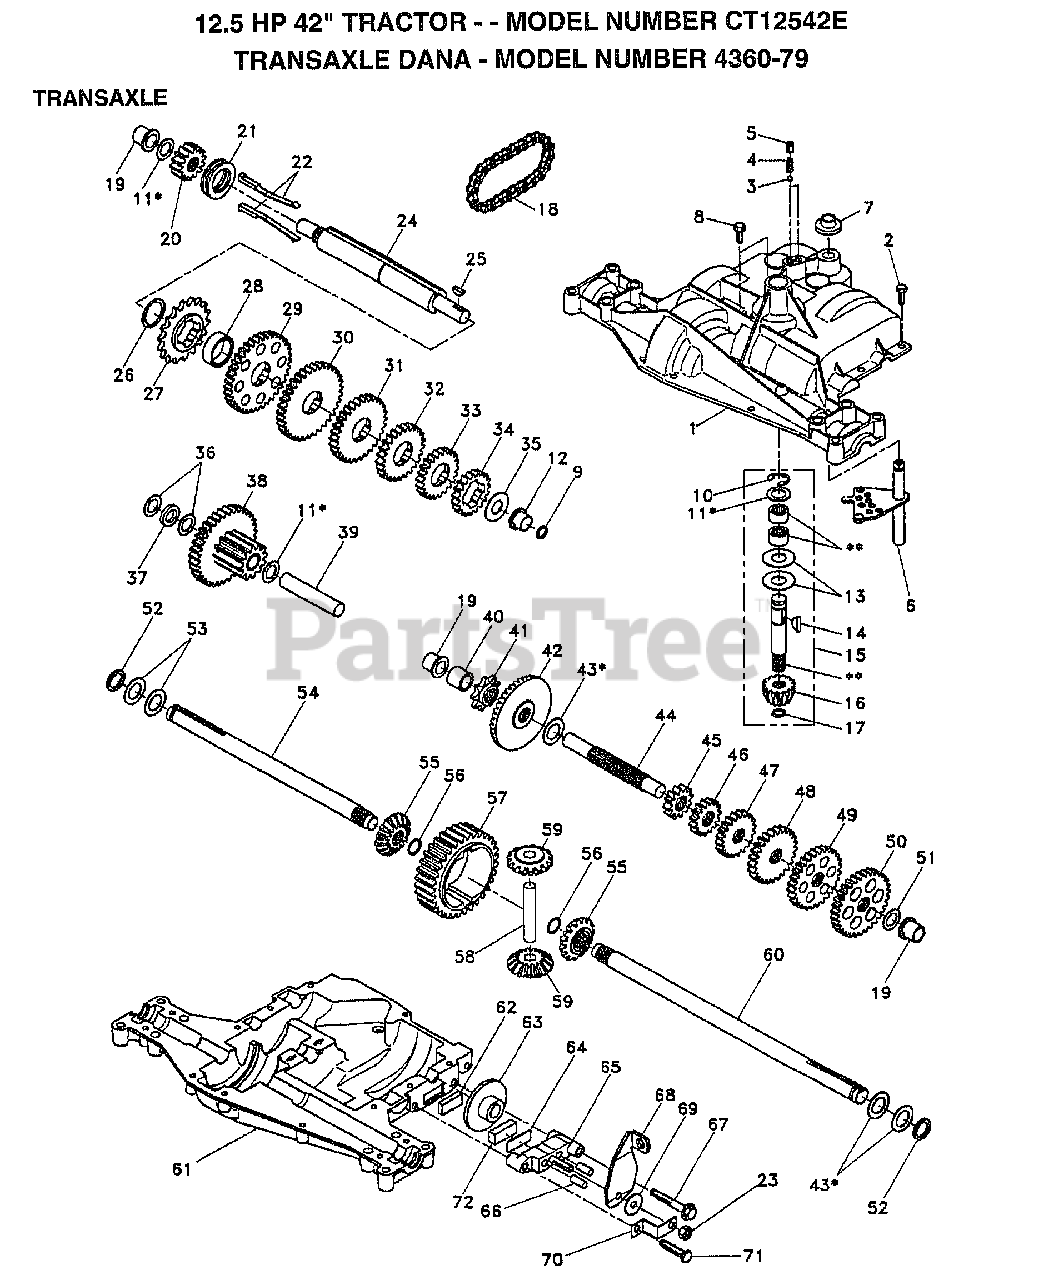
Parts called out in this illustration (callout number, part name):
1	HOUSING UPPER TRN
4	"SPRING, DETENT LT"
5	"SCREW, SET LT"
6	KIT SHIFTER ASM
7	SHIFTER BOOT
8	SCREW TAP W/SEAL
9	SQUARE RING
11	ASM KIT SHIM 4689
12	BEARING FLAN-DANA
13	WASHER T
14	KEY WOODRUFF-DANA
15	AS KIT INPUT SHFT
16	PINION 14T T
17	"RING,RETAINING LT"
18	"CHAIN,24 PTCH LT"
19	BEARING.FLNG.5510
20	GEAR SPUR 14 TTH
21	COLLAR CLUTCH
22	ASM KIT CLTCH KEY
23	NUT.LOCK.5/16-24
24	SHAFT INTERM DANA
25	WOODRUFF KEY
26	"RING,RETAINING LT"
27	SPROCKET 18T T
28	SPACER YT
29	GEAR SPUR 37 TTH
30	GEAR SPUR 35 TTH
32	GEAR 25T LT
33	GEAR SPUR 22 TT
34	SPUR GEAR 19T
35	"WASHER, PLAIN LT"
36	WASHER 025
37	SPACER
38	ASSM GEAR COMB
39	SHAFT IDLER
40	SPACER T
41	SPROCKET 9T LT
43	ASM KIT SHIM
44	SHAFT T
45	GEAR SPUR 12 TTH
46	GEAR SPUR 15 TTH
48	"GEAR, SPUR 25T LT"
49	GEAR 28T T
50	"GEAR, SPUR 31T LT"
51	WASHER 060
52	NEOPRENE WASHER
53	WASHER 031
55	GEAR 15T T
56	"RING,RETAINING LT"
58	SHAFT T
59	GEAR 1ST T
61	HOUSING LOWER TNS
62	PUCK T
63	BRAKE DISC. T
64	SPACER LT
66	PIN T
69	WASHER LT
71	"SCREW, TAPPING LT"
72	PUCK T
